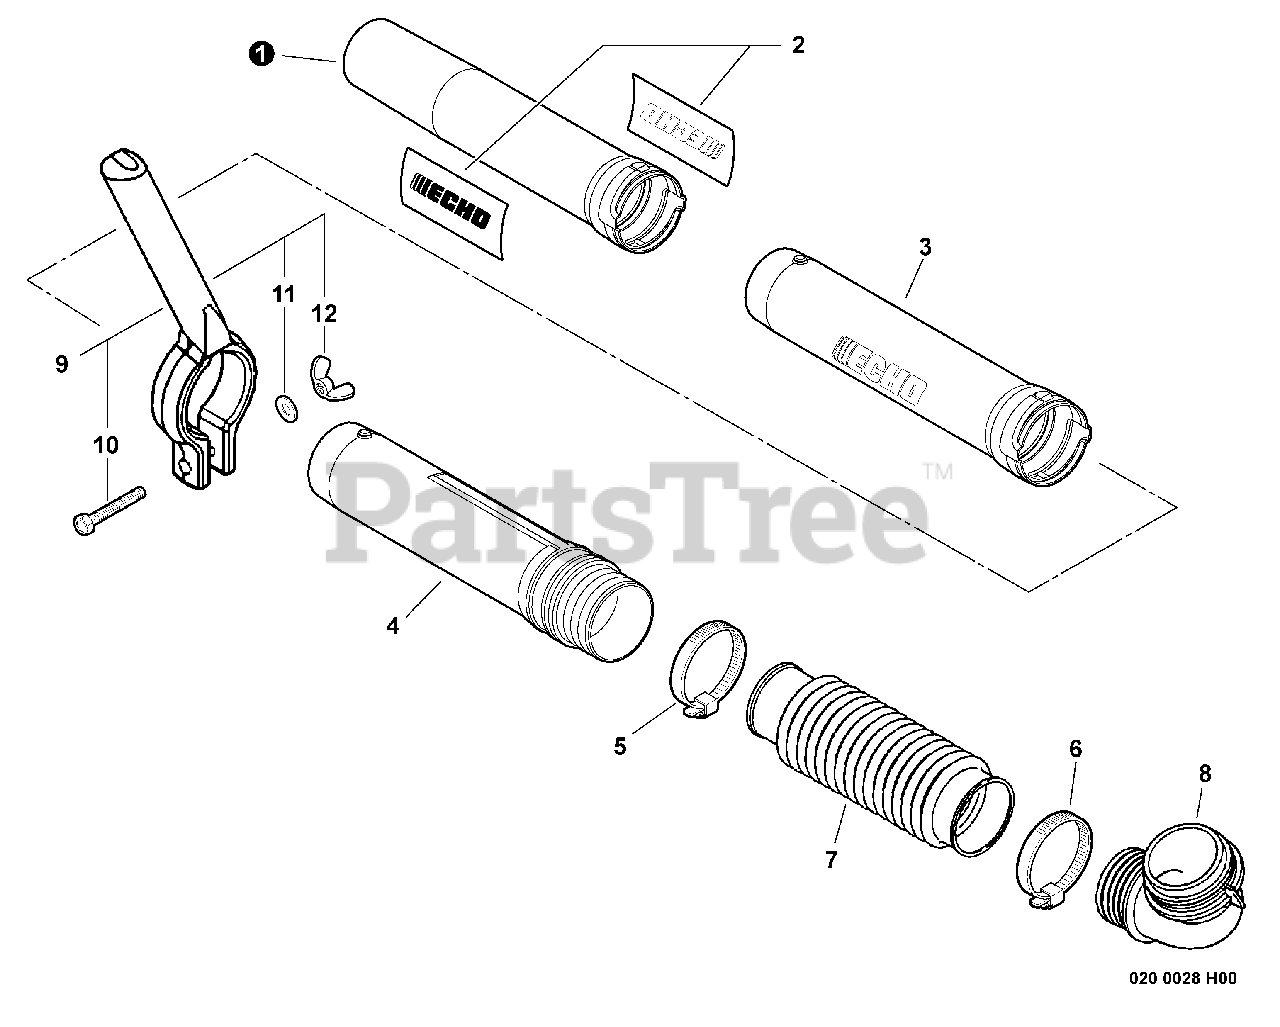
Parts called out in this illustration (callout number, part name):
1	TUBE, BLOWER - NOZZLE
2	LABEL - ECHO
3	TUBE, BLOWER - STRAIGHT
4	TUBE, BLOWER - SWIVEL
5	CLAMP, HOSE
6	CLAMP, HOSE
7	TUBE, BLOWER - FLEXIBLE
8	TUBE, BLOWER - ELBOW
9	TUBE MOUNT HANDLE
10	BOLT - 6X45
11	WASHER - 6
12	WINGNUT - 6
